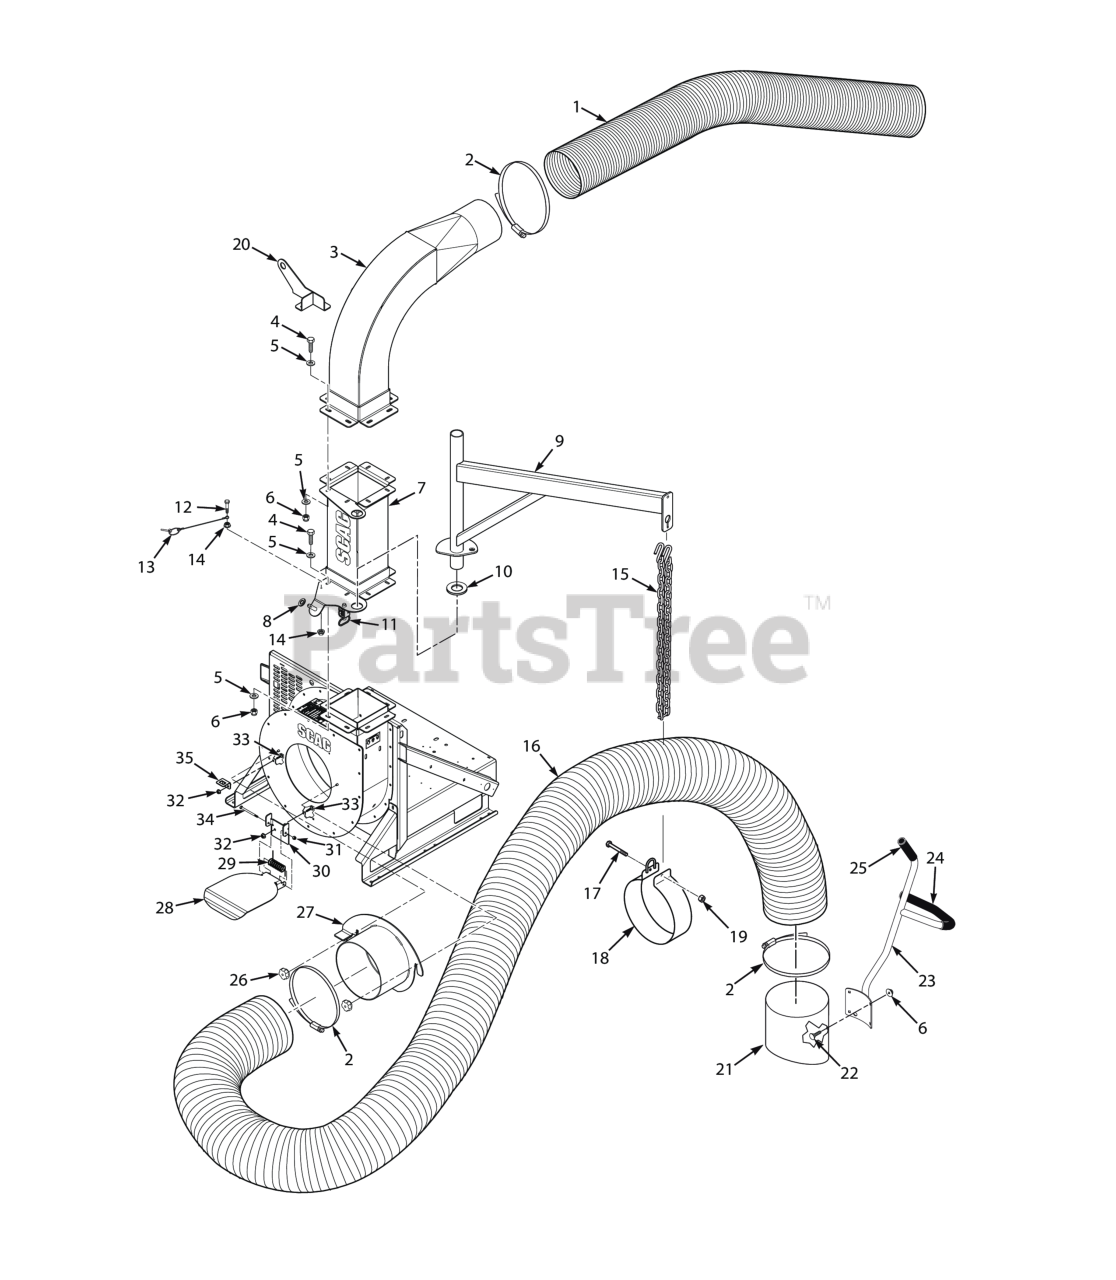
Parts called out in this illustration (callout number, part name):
1	Hose, Clear Poly 8" Dia. x 60"
2	Strap, Ratchet- 66 x 1"
3	Elbow, Exhaust - TL20W
4	Bolt, Hex Head 3/8-16 x 1-1/4", Kawasaki FX / FS
5	Flatwasher, 3/8" Special (.391 x .938 x .105)
6	HEX NUT, ELASTIC STOP LOCK, 3/8-16
7	Stack, Discharge w/Decals
8	Washer, Rubber
9	Boom Weldment
10	Disk, Anti-Friction
11	Spring
12	SERR. FLG. HEX HEAD CAPSCREW, 5/16-18 X 3/4
13	Quick Pin Assembly w/Lanyard
14	NUT, 1/4-20 SERRATED FLANGE HEX HEAD
15	Chain w/2-Hooks
16	Hose, 12" OD x 120" - .045 w/Wearstrip
17	Bolt, Hex Head 5/16-18 x 3-1/2"
18	Band, Hose Support
19	HEX NUT, ELASTIC STOP LOCK, 5/16-18
20	Bracket Weldment, Lift Hook
21	Nozzle, 12"
22	Carriage Bolt, 3/8-16 x 1.0"
23	Handle w/Grips
24	Grip, Handle 1-1/4" x 20"
25	Grip, Handle 1-1/4" x 6"
26	Knob, 3/8-16 Locking
27	Hose Mounting Weldment
28	Safety Switch Door
29	Spring, Discharge Chute
30	Mounting Bracket, Safety Switch Door
31	HEX NUT, ELASTIC STOP LOCK, 5/16-18
32	Nut, Serrated Flange 5/16-18 (Right Front Engine Mounting, Briggs and Kohler Only)
33	Bolt, Carriage 5/16-18 x 3/4"
34	Bolt, 5/16-18 x 4-3/4" Hex Head
35	Bracket, Brake Switch
